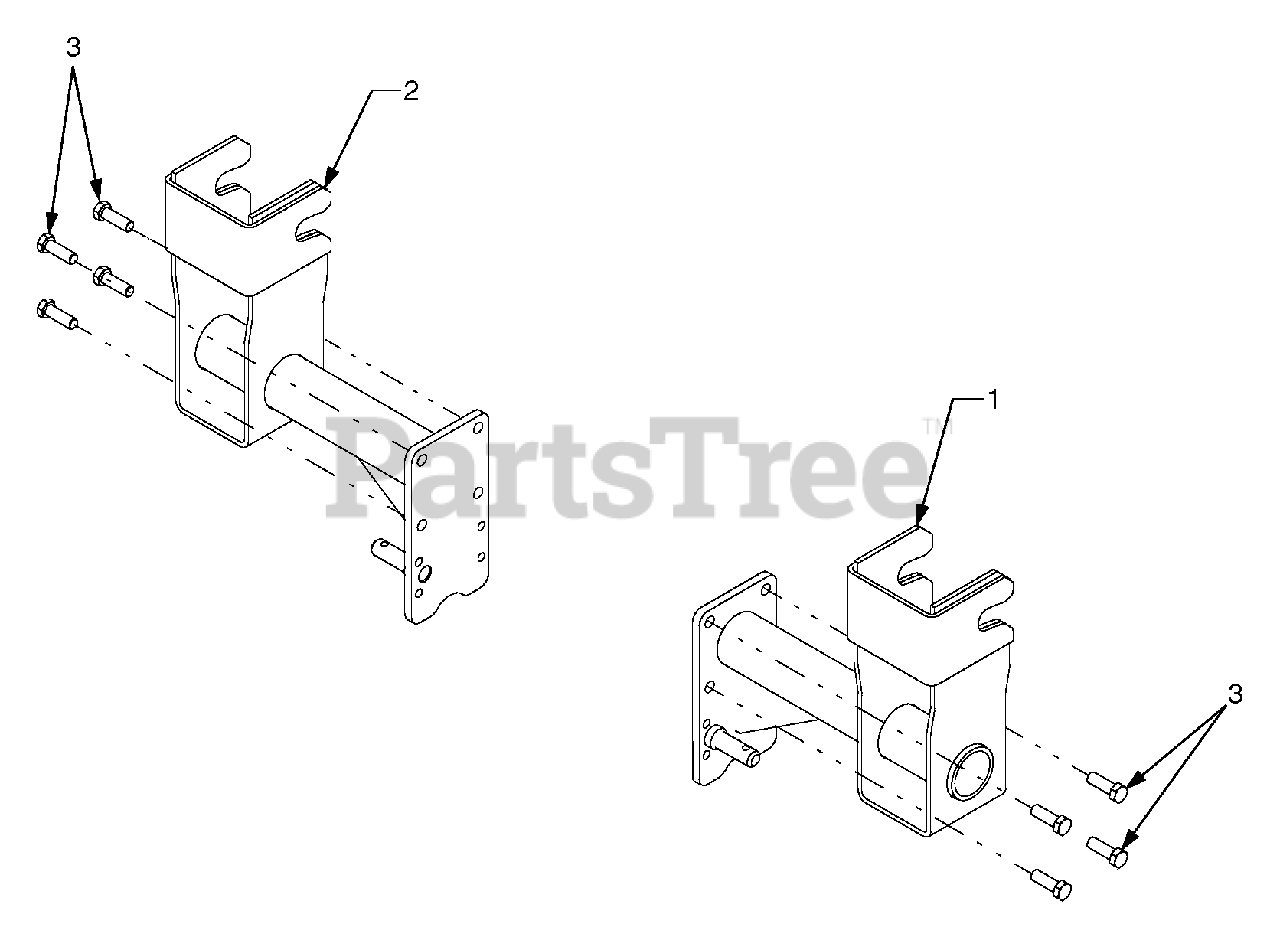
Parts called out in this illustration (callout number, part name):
1	Mount Assembly RH
2	Loader Mount Assembly LH
3	Hex Screw, 1/2-13, 1.50, Gr5
